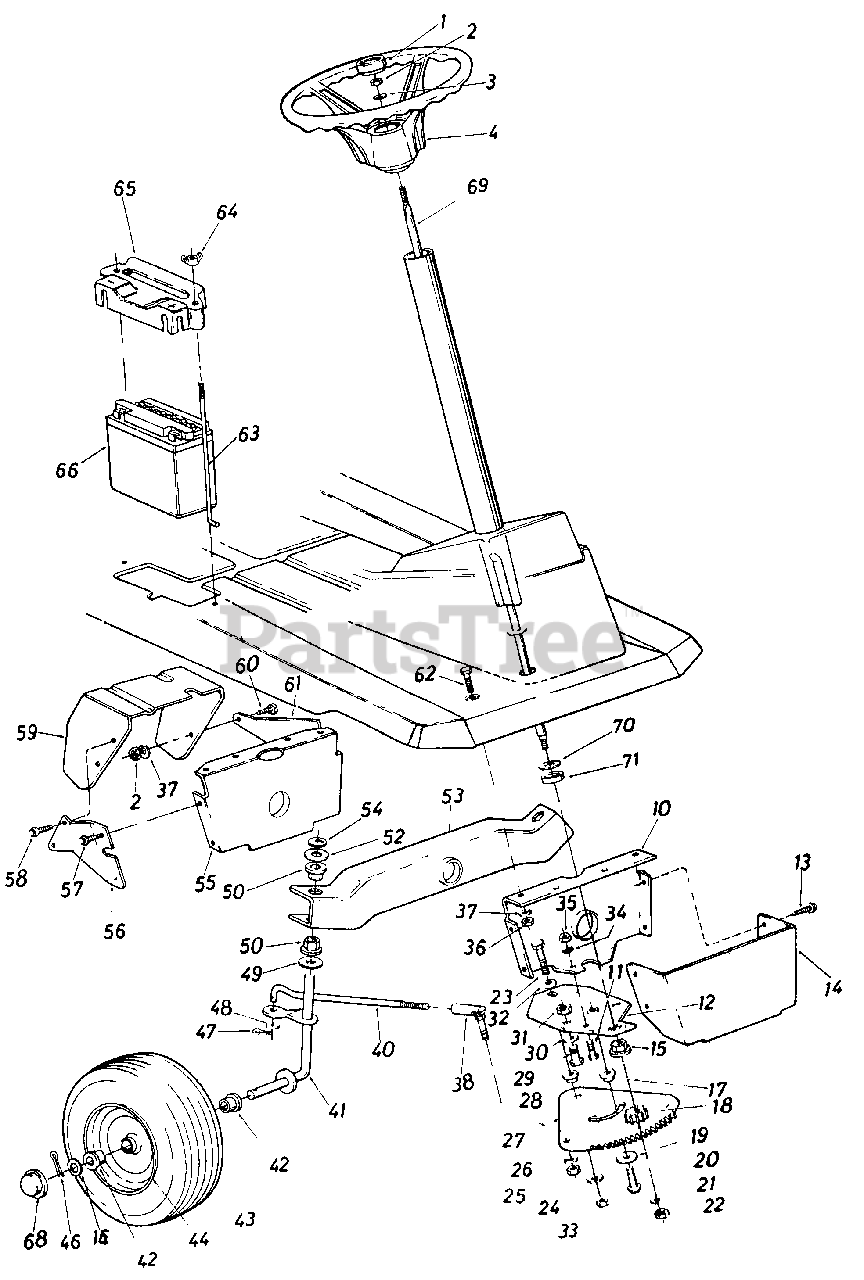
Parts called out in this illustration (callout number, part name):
1	Steering Wheel Cap
2	Hex Nut 5/16-18 Thd.
3	Bell-Wash. .345" I.D. x .88" O.D.
4	Steering Wheel Ass'y.
10	Pivot Bar Bracket
11	Hex Bolt 5/16-18 x .75" Lg*
12	Steering Gear Support Brkt.
13	Hex Wash. Hd. AB-Tap Scr 14 x 62" Lg.
17	Shoulder Spacer .622 Dia. x .218
18	Steering Pinion Gear
19	Fl-Wash. .385" I.D. x 1.38"
20	Hex Wash. Hd. Self-Tap Scr. 3/8-16 x 1.25" Lg.
21	Fl-Wash. .34" I.D. x .68" O.D.
22	Hex Nut 5/16-24 Thd*
23	Hex Bolt 3/8-24 x 1.25" Lg. (Grade 5)
24	Fl-Wash. .385" I.D. x 1.38"
25	Hex Nut 3/8-24 Thd*
26	L-Wash. 3/8" I.D*
27	Steering Gear Segment
28	Shoulder Spacer .622" Dia. x .21 8
29	Hex Bolt (Nylon) 1/2-13 x .75"
30	Fl-Wash. .530" I.D. x .930"
31	Hex Nut 1/2-13 Thd*
32	Bell-Wash. .385" I.D. x .88"
33	Hex Nut 3/8-24 Thd*
34	L-Wash. 5/16" I.D*
35	Hex Nut 5/16-18 Thd*
38	Ball Joint Ass'y. 3/8-24 Thd.
40	Steering Tie Rod
41	Front Axle Ass'y. R.H.
42	Flange Bearing .632" I.D.
43	Front Wheel Ass'y. Comp.
44	Front Wheel Rim Only
46	Cotter Pin 1/8" Dia. x 1.25"*
47	Cotter Pin 1/8" Dia. x 1.00"*
48	Fl-Wash. .385" I.D. x .87"
49	Fl-Wash. .635" I.D. x 1.12"
50	Hex Flange Bearing
52	Fl-Wash. .635" I.D. x 1.12"
53	Pivot Bar Ass'y.
54	Speed Nut 5/8" I.D.
55	Pivot Bar Bracket
56	Bracket Reinforcement R.H .
57	Hex Wash. Hd. AB-Tap Scr 1/4 x.62" Lg.
58	Cable Tie
59	Clutch-Brake Pedal Ass'y.
60	Hex Bolt 5/16-18 x .75" Lg*
61	Bracket Reinforcement L.H.
62	Hex Bolt 5/16-18 x .75" Lg*
63	Battery Hold Down Rod
64	Wing Nut Solid 1/4-20 Thd.
65	Battery Hold Down Cover
66	12 Volt Battery
68	Front Hub Cap
69	Steering Shaft Ass'y.
70	Fl-Wash. .62" I.D. x 1.50" O.D.
71	Spacer (Plastic)
